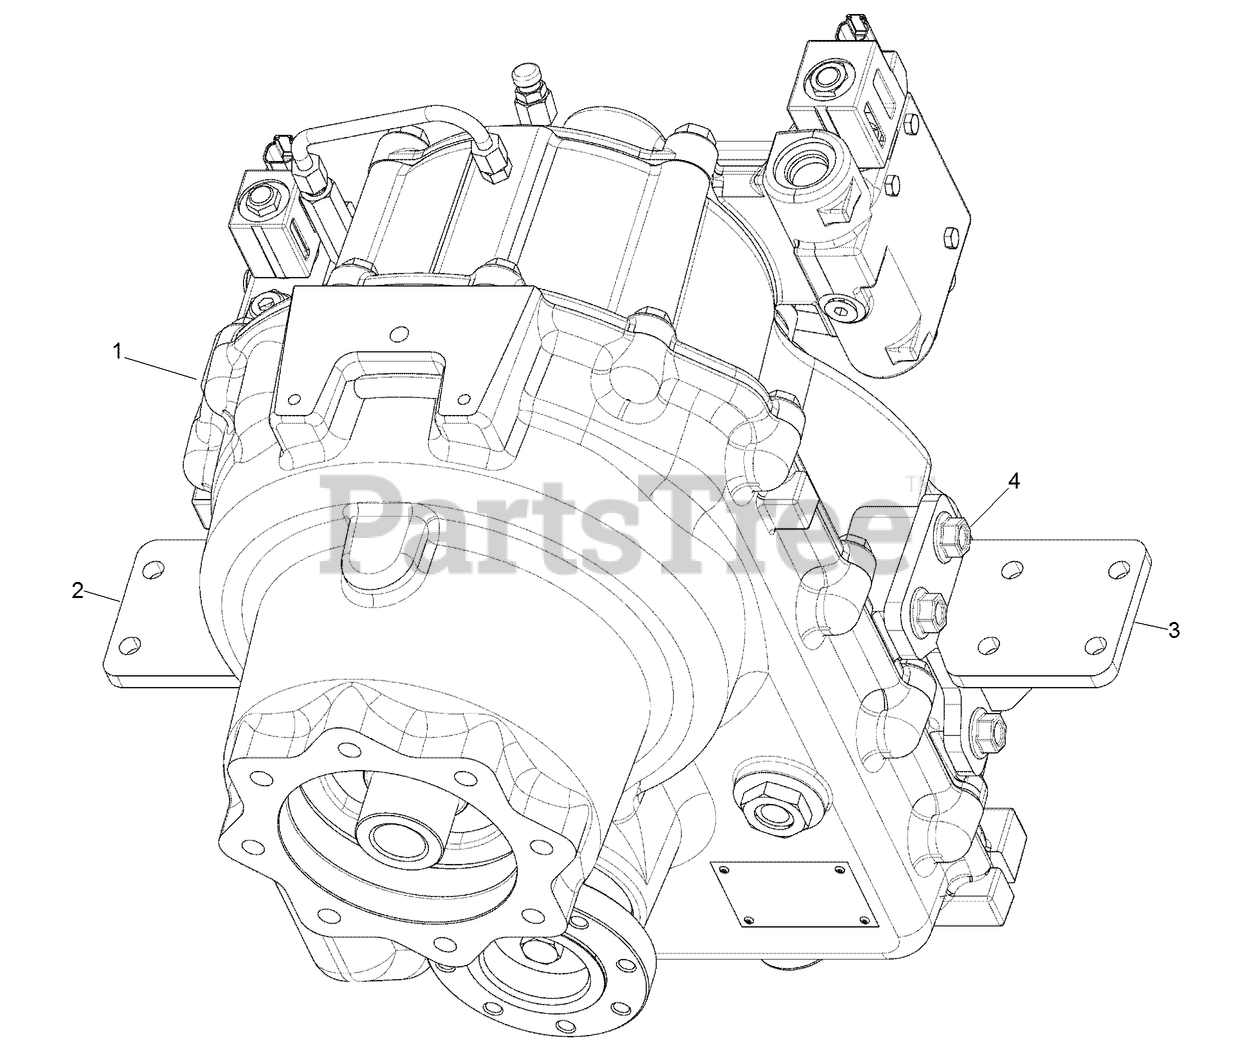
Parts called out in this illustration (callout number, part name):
1	TRANSMISSION-2 SPEED, POWERSHIFT
2	MOUNT-TRANSMISSION - RH
3	MOUNT-TRANSMISSION - LH
4	SCREW-HHF
